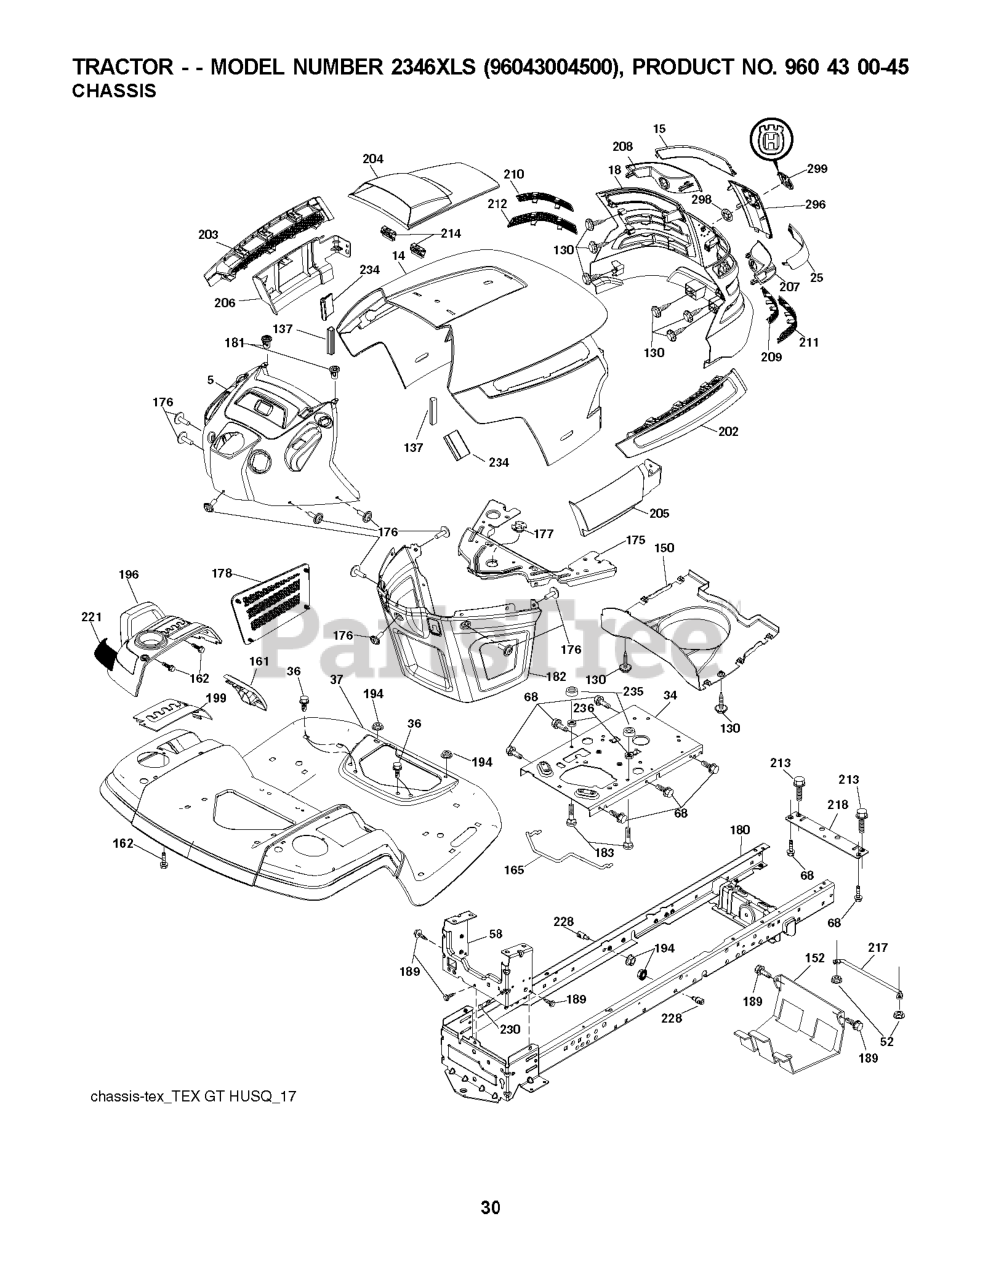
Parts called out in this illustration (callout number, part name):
5	DASH.ASM.HUSQ.GT.E.RECT.W/CK
14	HOOD
15	LENS.LH.TEX.GT.HUSQ.CL
18	GRILL.ASM.HUSQ.TG/CRD.W/TRIM
25	LENS.RH.TEX.GT.HUSQ.CL
34	PLATE.ENGINE.WELDED.CHASSIS
36	SCREW 5/16"
37	FENDER.PNT.TX.GT.CH/FW.ORANGE
52	LOCKNUT
58	DRAWBAR.LOWER.2PC,20"TIRES
68	Screw 5/16-18 x 1/2 Hex, Self Tapping 5/16-18 x 1/2
130	SCREW.#10 X 0.750.BOS
137	BUMPER DASH
150	AIR.DUCT.HOOD.TEX.GT.HUSQ
152	SHIELD.BROWNING.W/TEX
159	SCREW, 3/8-16X3/4
161	CONSOLE.FUEL.WINDOW.HU
162	Screw Hex WSH HI-LO 1/4 x 1/2 unc
165	SUPPORT.TANK.REAR.W/TEX
175	PLATE.CROSSMEMBER.HUSQ
176	SCREW.#10-24X5/8.RN.QU
177	BUSHING, STEERING
178	CARGO.ASM.NET.TXGT.W/C
180	CHASS.WLDMNT.TLT.12GA/2PC.20"
181	BUSHING.MNT.FEND.CRGO.
182	DASH.LOWER.COMMON.12V.ADAPTOR
183	BOLT.5/16-18X1-1/4 FULL.THREAD
189	SCREW
194	NUT LOCK HEX FLANGE 5/16-18
196	CONSOLE.ASM.DCKLFT.W/RF.HQ.DLR
199	PLATE.DECK.LIFT.HUSQVARNA.GT
202	VENT.SIDE.HOOD.HUSQ.RH.GREY
203	VENT.SIDE.HOOD.HUSQ.LH.GRAY
204	HOOD VENT
205	SKIRT.HOOD.SIDE.HUSQ.RH.GREY
206	SKIRT.HOOD.SIDE.HUSQ.LH.GREY
207	BEZEL.RH.TEX.GT.HUSQ
208	BEZEL.LH.TEX.GT.HUSQ
209	INSERT.HEX.GRILL.HUSQ.GREY
210	INSERT.HEX.GRILL.HUSQ.
211	INSERT.HEX.GRILL.HUSQ.
212	INSERT.HEX.GRILL.HUSQ.
213	BOLT
214	CLIP.RETAINER.TINNER.
217	ROD.PIVOT.HOOD
218	X-PIECE.HOOD.STOP.NON/
221	REFLECTOR.LH.TEX GT HU
228	STUD.FASTNER.W/ANTI-ROTATE
230	SHOULDER BOLT 5/16-18TT
234	BUMPER.HOOD.TEX.HUSQVARNA
235	SPACER FENDER
236	NUT.CENTERLOCK.5/16-
296	TRIM.HUSQ.TG/CRD.SERVICE
298	NUT PUSH M
299	RP LOGO
